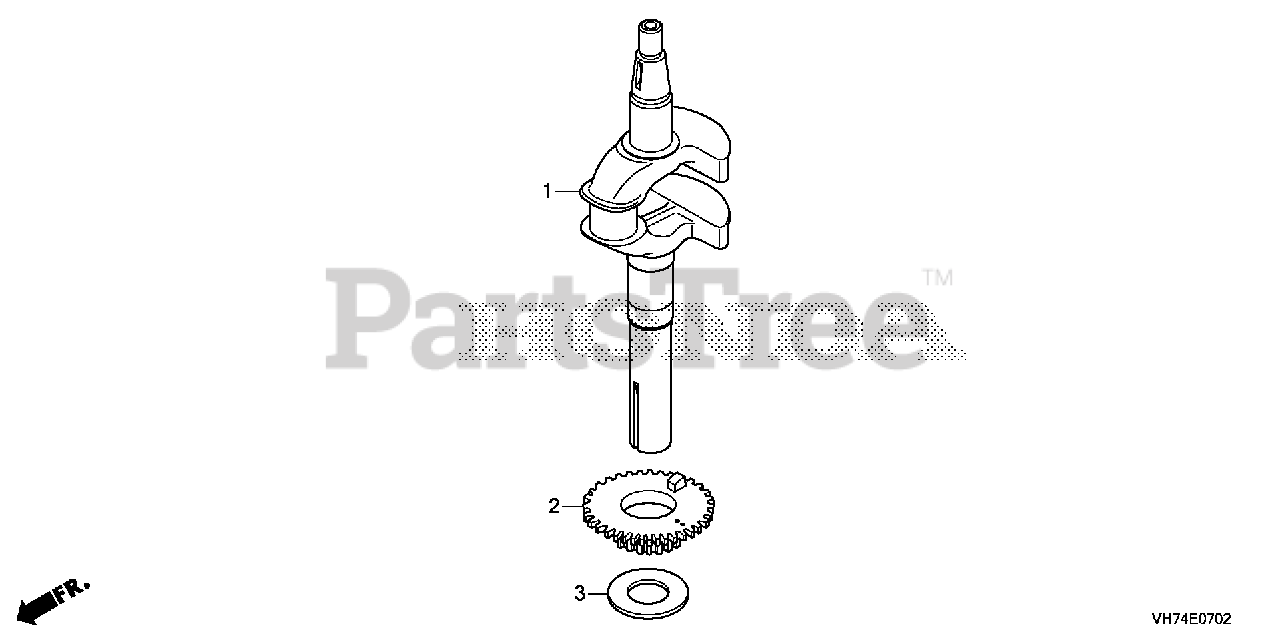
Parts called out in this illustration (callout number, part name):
1	CRANKSHAFT (HARD TYPE)
2	GEAR, TIMING
3	WASHER, THRUST
